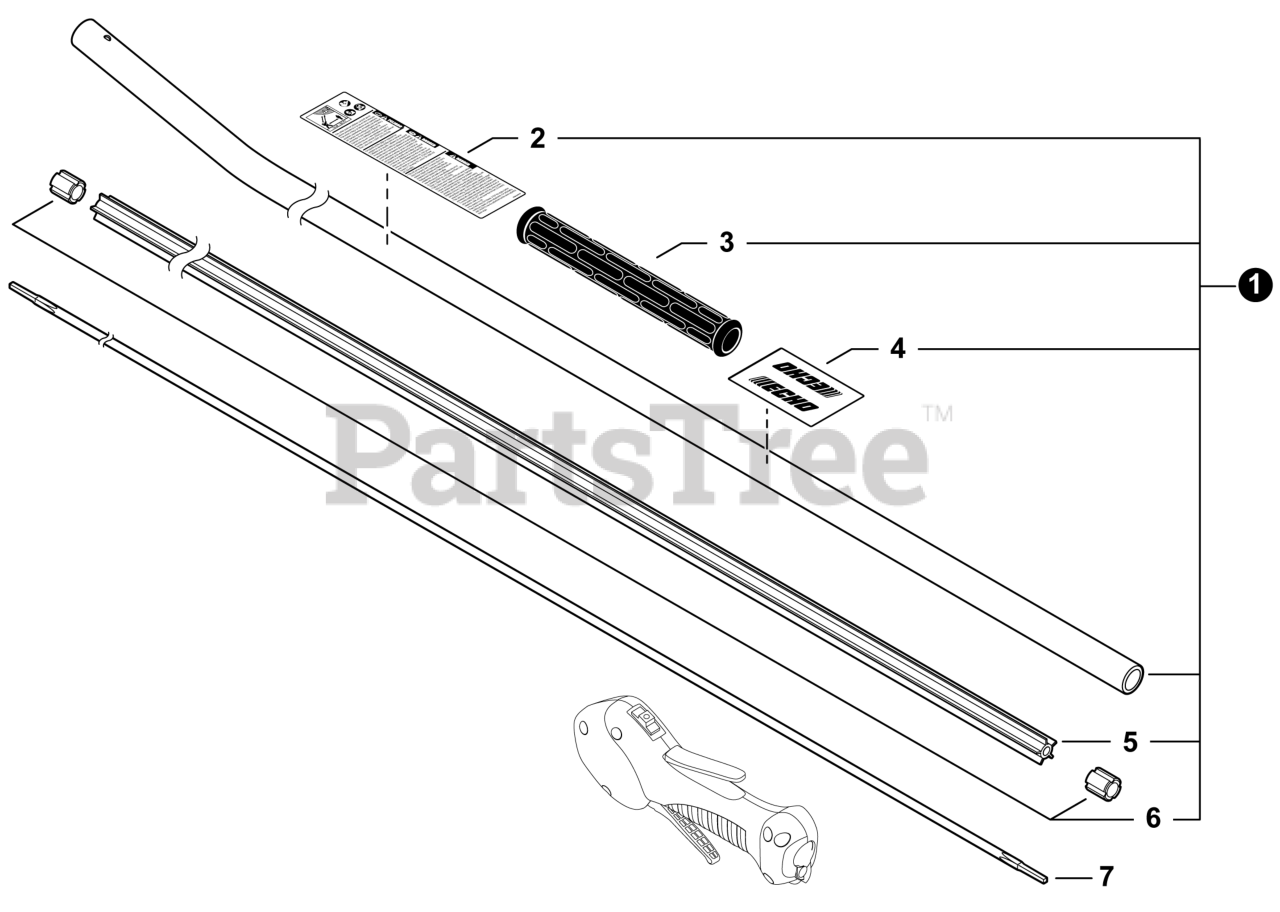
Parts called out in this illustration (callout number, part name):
1	MAIN PIPE ASSY
2	LABEL - CAUTION
3	GRIP, FRONT
4	LABEL - HANDLE LOCATION
5	LINER - FLEXIBLE
7	DRIVESHAFT - FLEXIBLE
